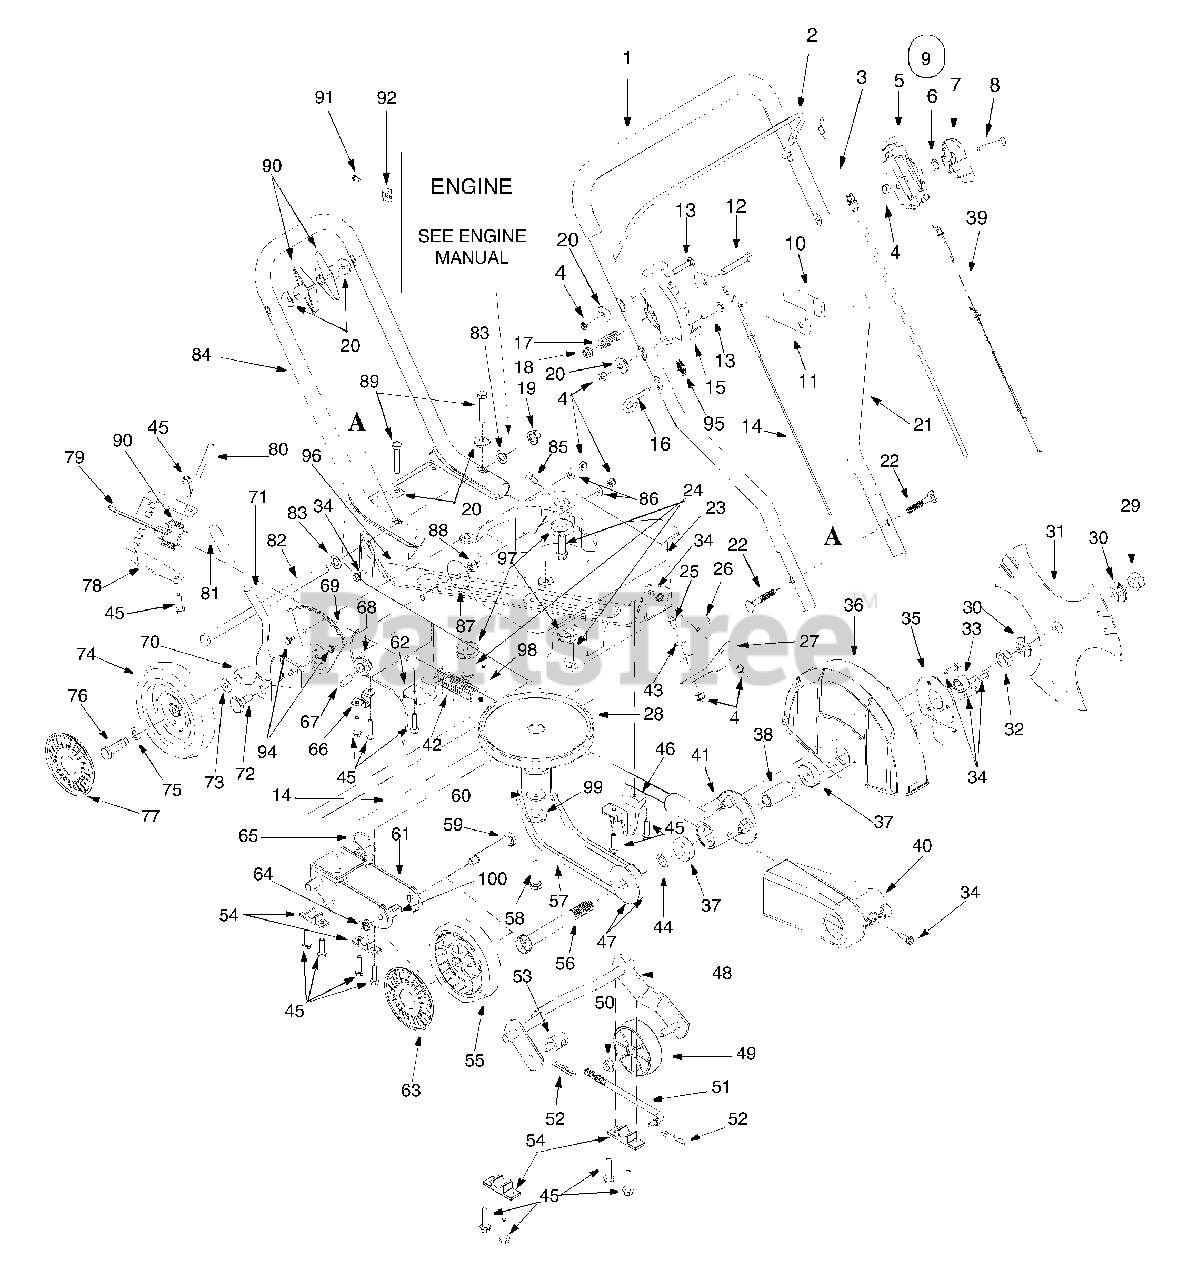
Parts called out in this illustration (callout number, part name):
1	Foam Grip
3	Control Cable 44" B & S
4	Hex Lock Nut 1/4-20 Thd.
5	Throttle Hsg.
6	Curved Washer .663 x .980 x .014
7	Throttle Lever
8	Screw Oval C-Sunk 1/4-20 x 1.81 Lg.
9	Throttle Comp.
10	Depth Lever Grip
12	Hex Screw 5/16-18 x 2.0 Lg.
13	Carriage Bolt 1/4-20 x 1.50 Lg.
14	Depth Cable
15	Depth Bracket
16	Eye Bolt 1/4-20
17	Compression Spring .550 O.D. x 1.3
18	Hex Lock Nut 5/16-18
19	Push Cap x 1/2 Rod
20	Washer .320 ID x .93 O.D.
23	Edger Base Ass'y
24	Tapp Screw w/Hex Lock Wash 3/8-16
25	Hex Screw 1/4-20 x .50 Lg.
26	Discharge Shield Deflector
27	Deflector Keeper
28	Engine Pulley
29	Hex Jam Nut 5/8-18
30	Bell Washer .63 I.D. x 1.25 O.D. x .18
32	Hex Jam Nut 5/8-18
33	Spacer .628 x .875 x .545 Lg.
34	Hx Scr. w/Wash.: TT: 1/4-20 x .750 Lg.
37	Ball Bearing .62 I.D. x 1.38 O.D. x .4
38	Spacer .628 x .875 x 1.818 Lg.
39	Throttle Cable
40	Belt Guard
41	Spindle w/Insert
42	Compression Spring: Arbor
43	Flat Washer .283 I.D x .75 O.D. x .030
44	Flat Washer .635 I.D. x .93 O.D. x .06
45	Hex Screw w/Wash 1/4
46	Front Rod Handler
47	Pulley
50	Push Cap x 3/8 Rod
51	Rod 5/16-24
52	Cotter Pin .072 x 1.12
53	Ferrule 5/16-24 x .312
54	Black Bushing .515 Dia x .62
55	Wheel 7 x 1.7 Aero Gray
56	Hex Bolt 5/8-18 x 5.25 Lg.
57	V-Belt
58	Hex Screw: 3/8-24 x 1.50 Lg.
59	Shoulder Screw .500 x 2.62: 3/8-16
60	Bell Wash..396 I.D. x 1.140 O.D. x .095
61	Front Wheel Brkt Ass'y.
62	Rear Rod Handler
63	Hubcap: Spoke w/Hole Gray
64	Jam Lock Nut 3/8-16
65	Torsion Spring
68	Cable Roller Pulley
69	Index Plate
70	Pivot Arm
71	Spring Lever
72	Shoulder Bolt .500 x .434 Lg.
73	Bell Wash. .401 ID. x .870 OD. x .063
74	Wheel: 8 x 1.7 Aero Gray
75	Wave Washer .510 I.D. x .750 O.D.
76	Shoulder Bolt .498 x 1.445: 3/8-16
77	Hubcap: Radial Spoke Gray
78	Tilt Bracket
79	Adj. Lever Ass'y
80	Pin 1/4 x 2.0" Lg.
81	Foam Grip
83	Flat Wash. .531 I.D. x .875 O.D. x .06
86	Flat Wash. .285 ID x 1.25 OD x .06
87	Flat Wash. .406 ID x 1.92 OD x .06
88	Hex Lock Nut 3/8-16
89	Hex Screw 5/16-18 x 1.75 Lg.
90	Torsion Spring
90	Wing Knob Nut 5/16-18
91	Hex Scr. w/Wash.:T: #10-32 x .625 Lg.
92	Clamp B&S Throttle
94	Screw Std. 1/4-20 x .75 Lg.
95	Handle Knob
98	Roll Pin
99	Flat Washer .38 ID x 1.38 OD x 1.25
100	Spacer .520 ID x .860 Lg.
